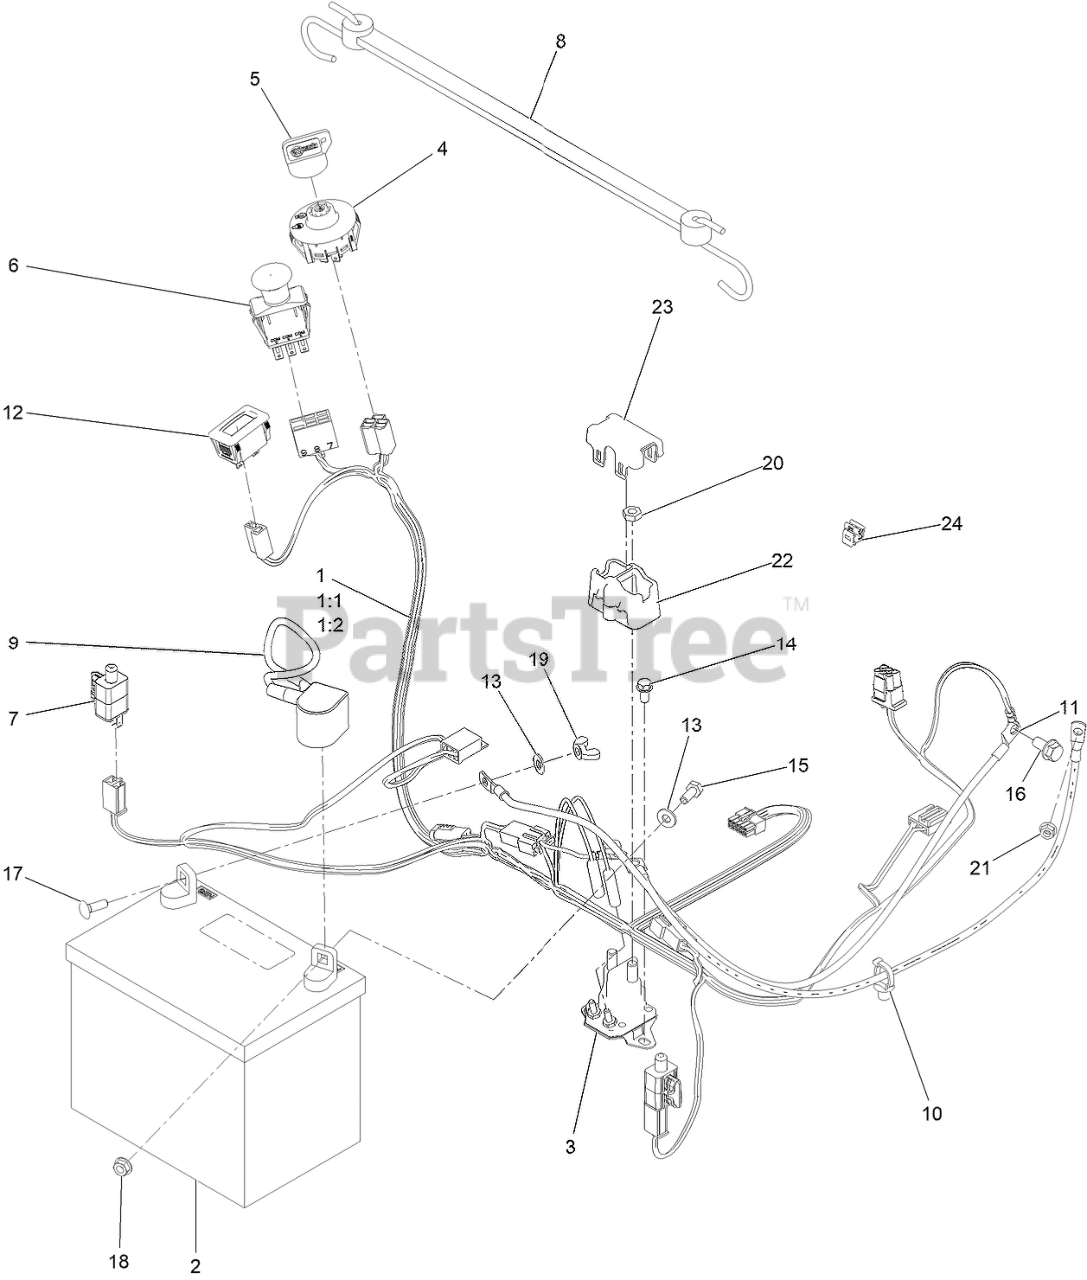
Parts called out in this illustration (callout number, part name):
1	HARNESS-WIRE
1:1	FUSE-BLADE, 15 AMP
1:2	FUSE-BLADE, 25 AMP
2	BATTERY
3	SOLENOID
4	SWITCH-IGNITION
5	KEY-IGNITION
6	SWITCH-PTO
8	STRAP-RUBBER
9	CABLE-BATTERY, POS
10	CABLE-BATTERY, RED (8 GAUGE)
11	CABLE-BATTERY, BLACK
12	HOURMETER
13	WASHER-FLAT
14	SCREW-HWH
15	SCREW-HH
16	SCREW-HHF
17	BOLT-CARR
19	NUT-WING
20	NUT-JAM
22	COVER-SOLENOID
23	CAP-SOLENOID
24	CLIP-HARNESS
